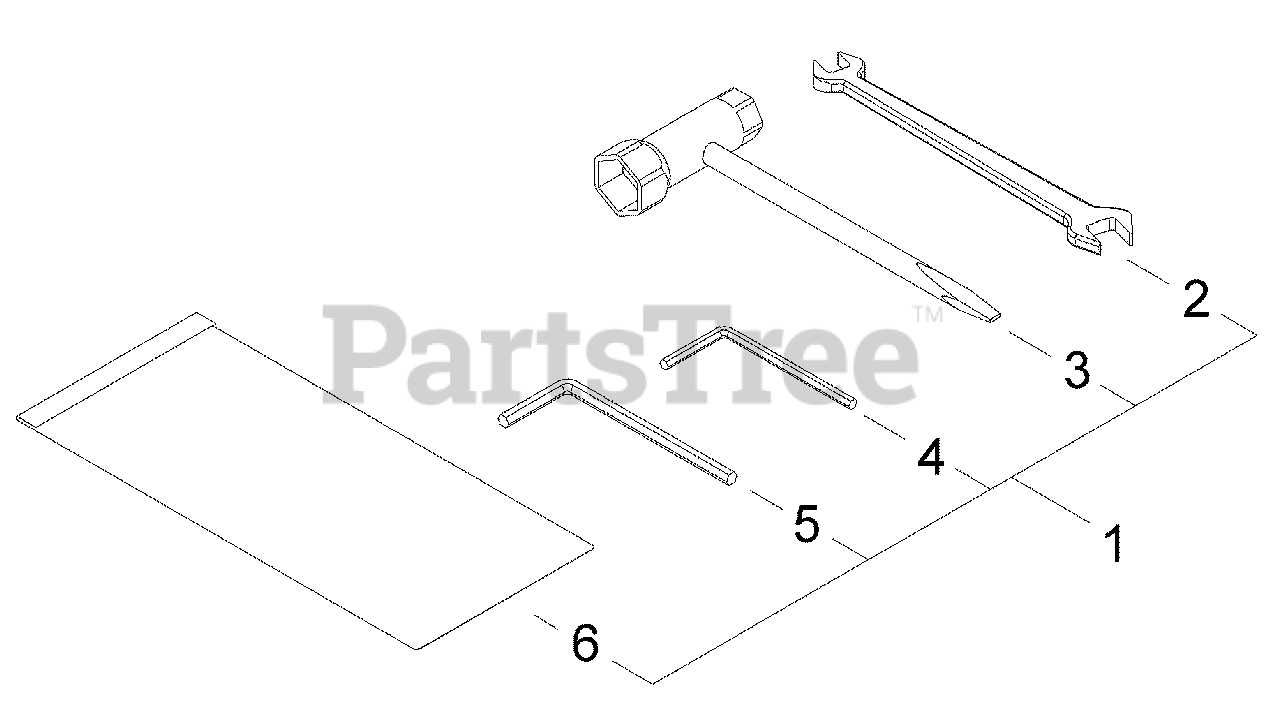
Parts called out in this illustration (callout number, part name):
1	TOOL KIT
2	SPANNER - 8X10mm
3	T-WRENCH - 13X16mm
4	HEX KEY - 4mm
5	HEX KEY - 6mm
6	BAG, TOOL
